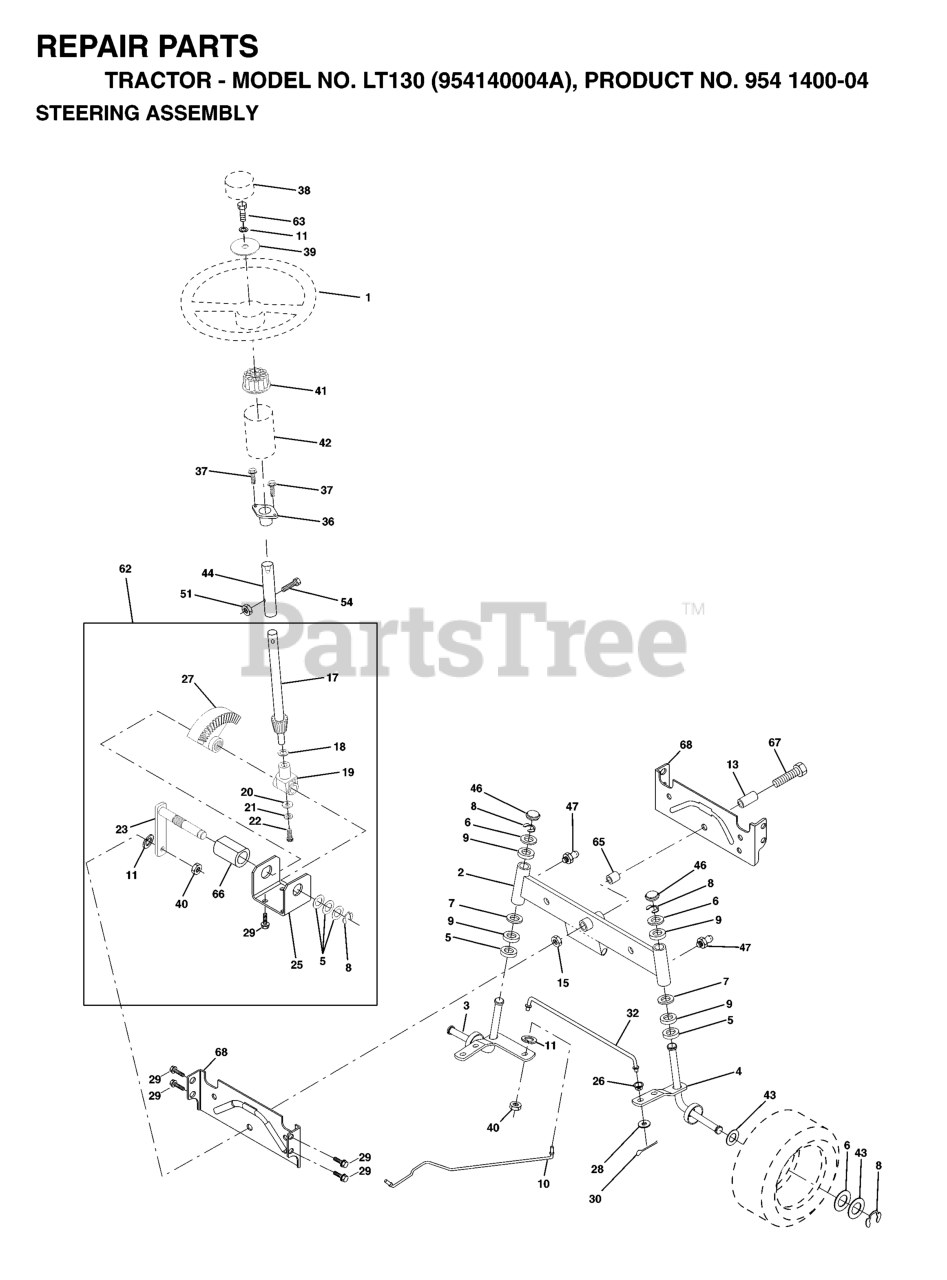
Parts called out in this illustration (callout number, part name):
1	STEERING WHEEL
2	AXLE ASSY
3	SPINDLE.ASM.LH
4	SPINDLE ASM, RH
5	THRUST WASHER
9	BRNG T
10	DRAGLINK-STAMPED
11	WASHER, LOCK 3/8
13	BEARING AXLE
15	NUT-LOC,FLANGE LT
17	SHAFT ASM STEERING
18	THRUST WASHER
19	SHAFT,SUPPORT
20	WASHER
21	LOCKWASHER
22	SCREW
23	SHAFT PITMAN
25	BRACKET STEERING
26	BUSHING.DRAGLINK (2 2)
27	GEAR.SECTOR
28	WASHER
29	SCREW
30	COTTER PIN
32	TIE ROD
36	BUSHING, STEERING
37	SCREW.TT.#10-32X.5.3/8.FLANGE
38	INSERT,STR WHEEL
39	WASHER T
40	GRIPCO NUT
41	ADAPTER LT
42	BOOT, STEERING
44	EXT SHAFT STEERING
46	CAP.SPINDLE.BLACK
47	ZERK M
51	NUT.71038.31-18.HEX.NYLOCK
54	BOLT.5/16-18X1-1/4 FULL.THREAD
62	KIT, STEERING ASSEMBLY
63	BOLT
65	SPACER AXLE
66	BEARING ARM
67	Bolt, Hex 5/8 -11 x 2 - 3/4 Gr. 5
68	AXLE, BRACE
